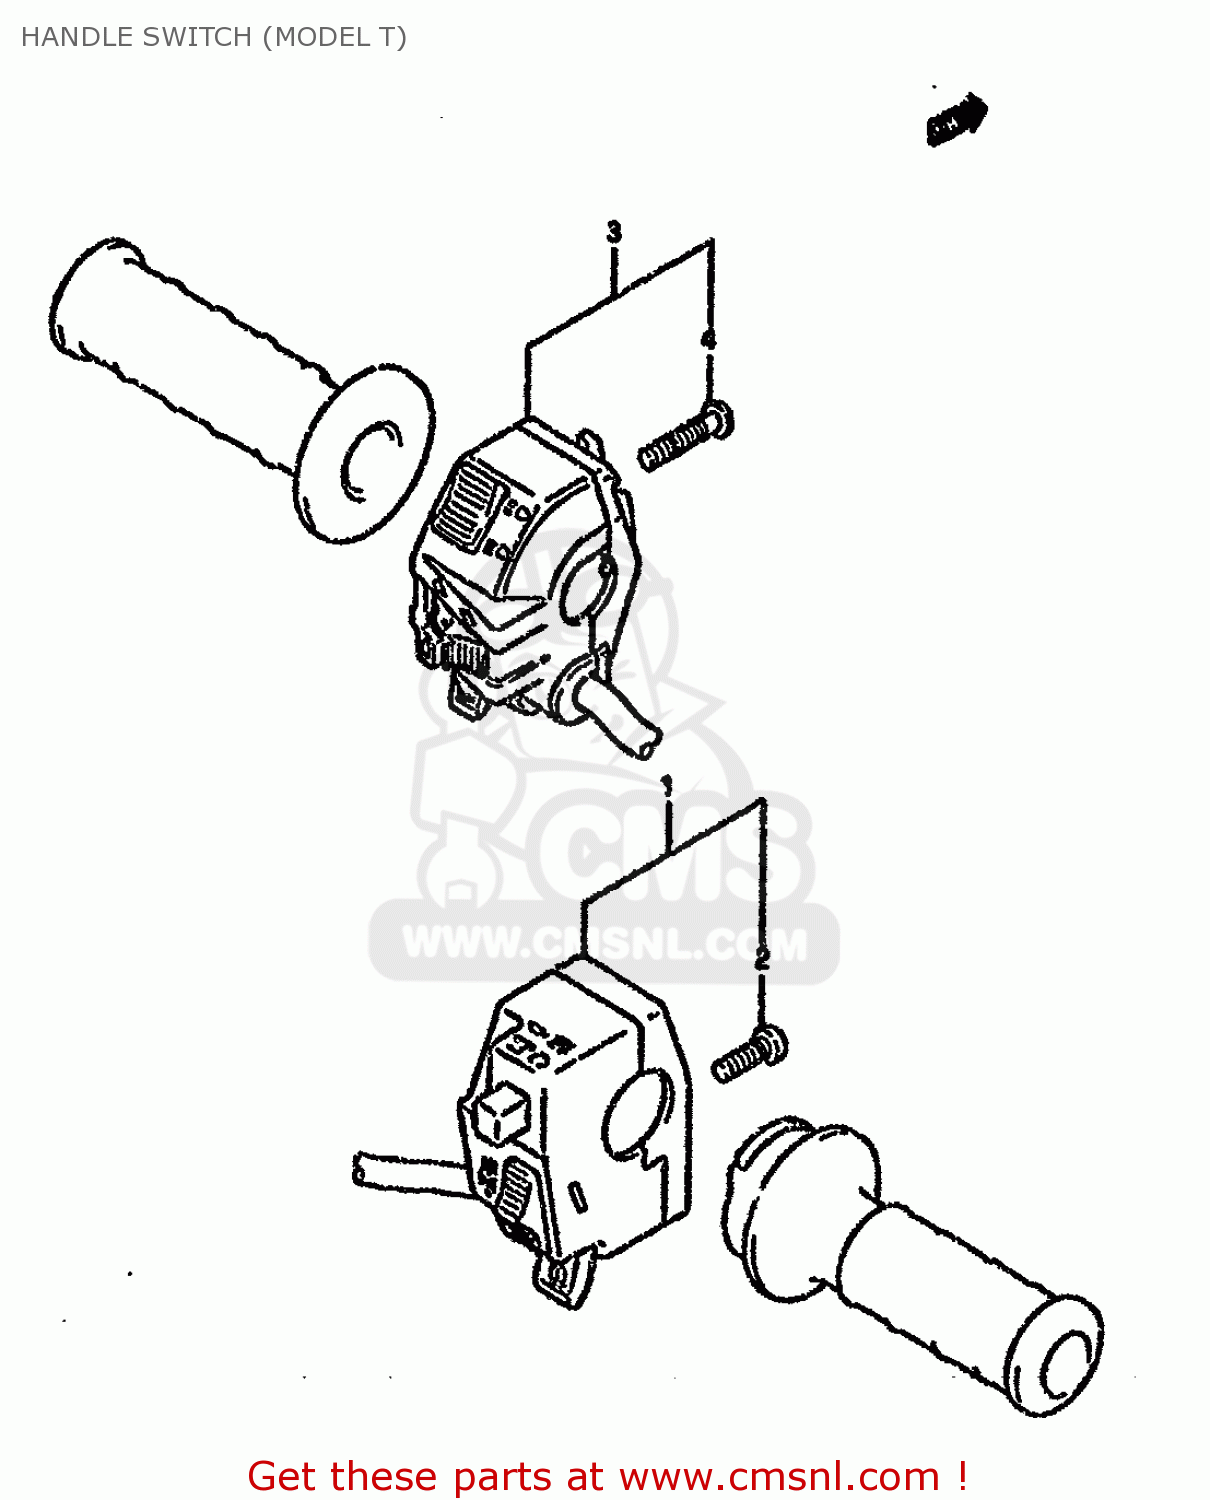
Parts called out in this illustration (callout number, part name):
1	SWITCH ASSY,HANDLE,R
2	SCREW
3	SWITCH ASSY,HANDLE,LH
4	SCREW
